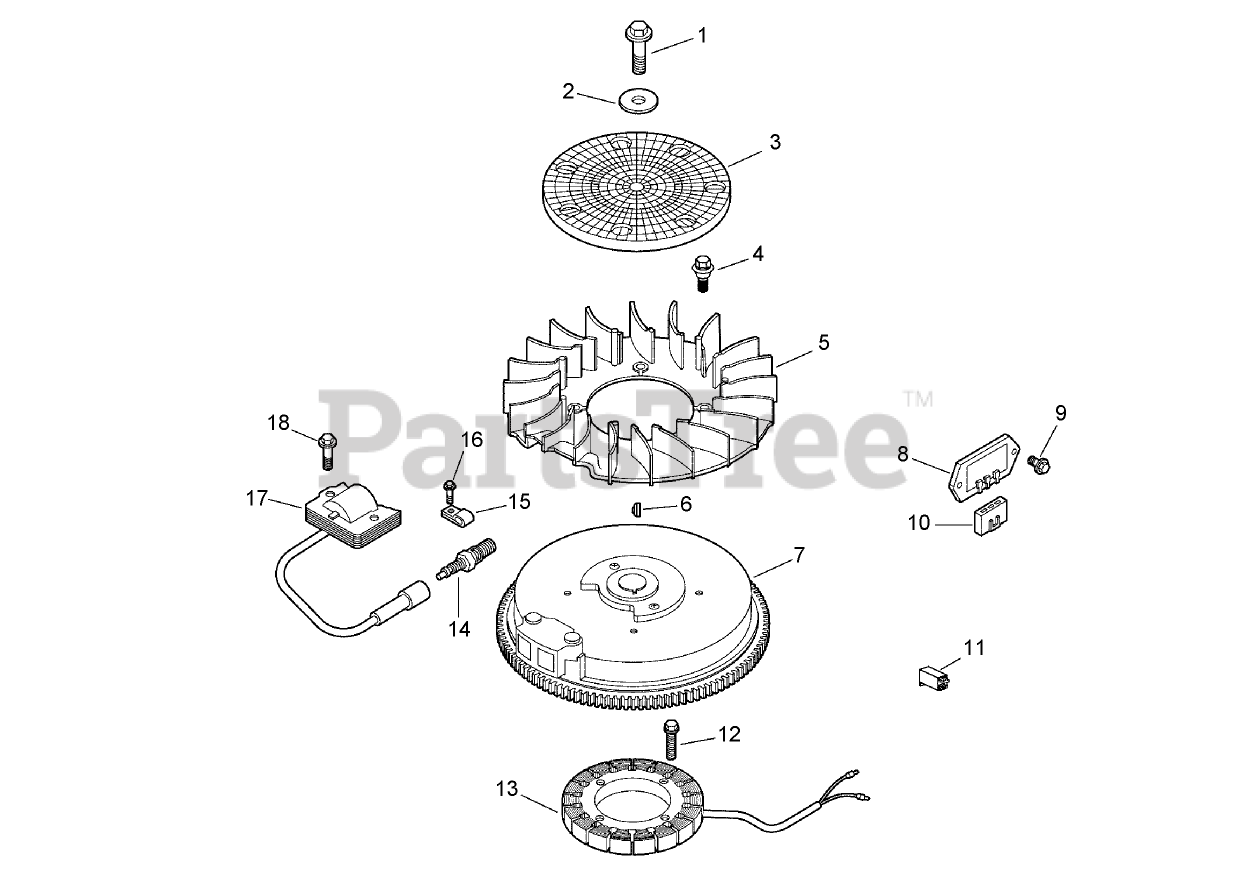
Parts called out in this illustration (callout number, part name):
1	SCREW-FLANGE (M10X1.5X45)
2	WASHER-FLAT (13/32)
3	Screen-Grass
4	BOLT-SHOULDER (M6x1.0x16)
5	Fan
6	KEY (3/16 X 5/8)
7	Flywheel
8	Rectifier-regulator
9	Screw-HF (M6x1.0x16)
10	Connector (3 contact)
11	Connector
12	SCREW-THREAD FORMING (M5X0.8X25)
13	Stator Kit (Includes 25 452 01-S)
14	SPARK PLUG
15	Clip
16	SCREW-HHFTF (M5X.80X10)
17	Module-Ignition
18	SCREW-FLANGE, THREAD FORMING (M5X.8X20)
